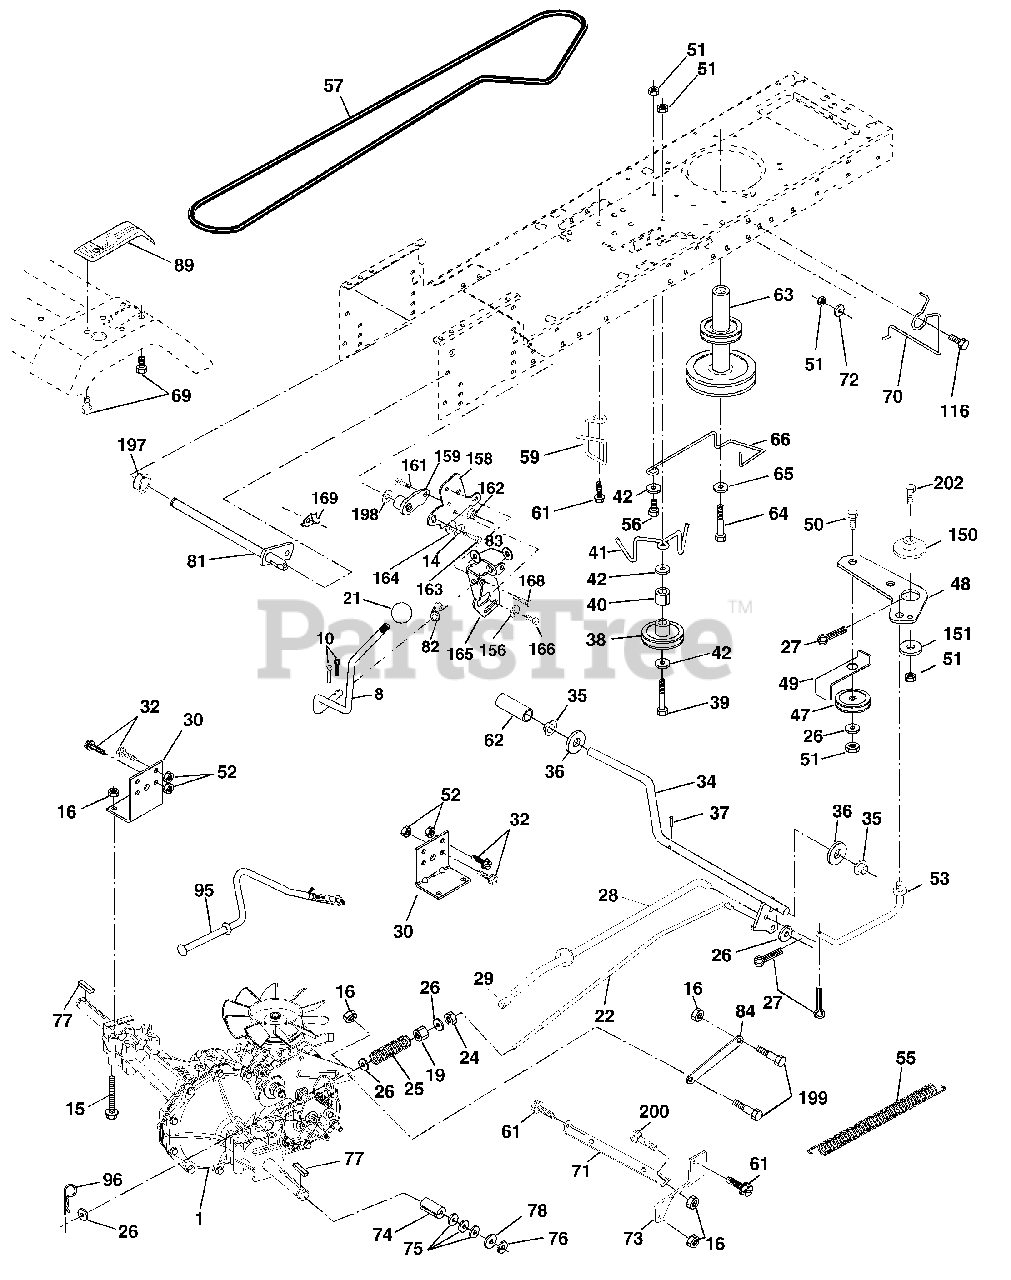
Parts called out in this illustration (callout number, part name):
8	Rod Shift Hydro LT
10	Pin Cotter 1/8 x 1 CAD
14	Washer Lock Hvy Helical
15	Bolt, Hex FLGHD 5/16-18 Gr. 5
16	Nut Lock Hex W/Ins 5/16-18 Unc P
19	Nut Lock Hex W/Wsh 3/8-16 Unc
21	Knob, Round 1/2-13
22	Rod, Brake Hydro
24	Nut
25	Spring, Brake Rod
26	Washer
27	Pin Cotter 1/8 x 3/4 CAD.
28	Rod, Parking Brake
29	Cap, Parking Brake
30	Bracket, Transaxle
32	Bolt Hex Hd 5/16-18 Unc x 3/4
34	Shaft, Foot Pedal
35	Bearing, Nylon
36	Washer
37	Pin, Roll
38	Pulley, Idler, Flat
39	Bolt
40	Spacer, Split
41	Keeper, Belt Idler
42	Washer 13/32 x 13/16 x 12 Gauge
47	Pulley, Idler, V-Groove
48	Bellcrank Clutch Grnd Drv STL
49	Retainer, Belt
50	Bolt
51	Nut Crownlock 3/8-16 UNC
52	Nut Crownlock 5/16-18 UNC
53	Link, Clutch
55	Spring, Return, Clutch
56	Bolt Fin Hex 3/8-16 UNC x 1-1/4
57	V-Belt, Ground Drive
59	Keeper, Center Span
61	Screw Thdrol. 3/8-16 x .75
62	Cover, Pedal
63	Pulley, Engine
64	Bolt, Hex
65	Washer
66	Keeper Belt Engine
69	Screw
70	Guide Belt
71	Strap Torque Lh Hydro
72	Washer 13/32 x 1-1/4 x 12 Gauge
73	Strap Torque Rh Hydro
74	Spacer, Axle
75	Washer 25/32 x 1-1/4 x 16 Gauge
76	E-Ring
77	Key, Square
78	Washer 25/32 x 1-5/8 x 16 Gauge
81	Shaft Asm. Cross Hydro
82	Spring Torsion T/A
83	Washer 17/32 x 3/4 x 16 Ga.
84	Link Transaxle
89	Console, Hydro
95	Control Asm Bypass Hydro
96	Retainer Spring 1" Zinc/Cad
116	Bolt Rdhd Sq Neck 3/8-16 x 1.25
150	Bushing Bellcrank Grd Drive
151	Washer 13/32 x 2 x 10 Ga.
156	Washer Srrted 5/16 ID x 1.125
158	Bracket Shift Mount
159	Hub Tapered Flange Shift Lt
161	Bolt Rdhd Sqnk 1/4-20 x 3/4 Gr 5
162	Nut Crownlock 1/4-20 Unc
163	Bolt Hex Fin 1/4-20 Unc x 1 Gr 5
164	Washer 5/8 x .281 x 10 Ga
165	Bracket Pivot Lever
166	Screw 5/16-18 x 5/8
168	Bolt Shoulder 5/16-18 x .561
169	Plate Fastening Lt
197	Nyliner Snap-In 5/8" ID
198	Washer Nyl 7/8 ID x .105
199	Bolt Shoulder 5/16-18 Unc
200	Bolt Rdhd Sqnk 5/16-18 Unc x 1
202	Bolt Carr Sh 3/8-16 x 1-1/2 Gr 5
